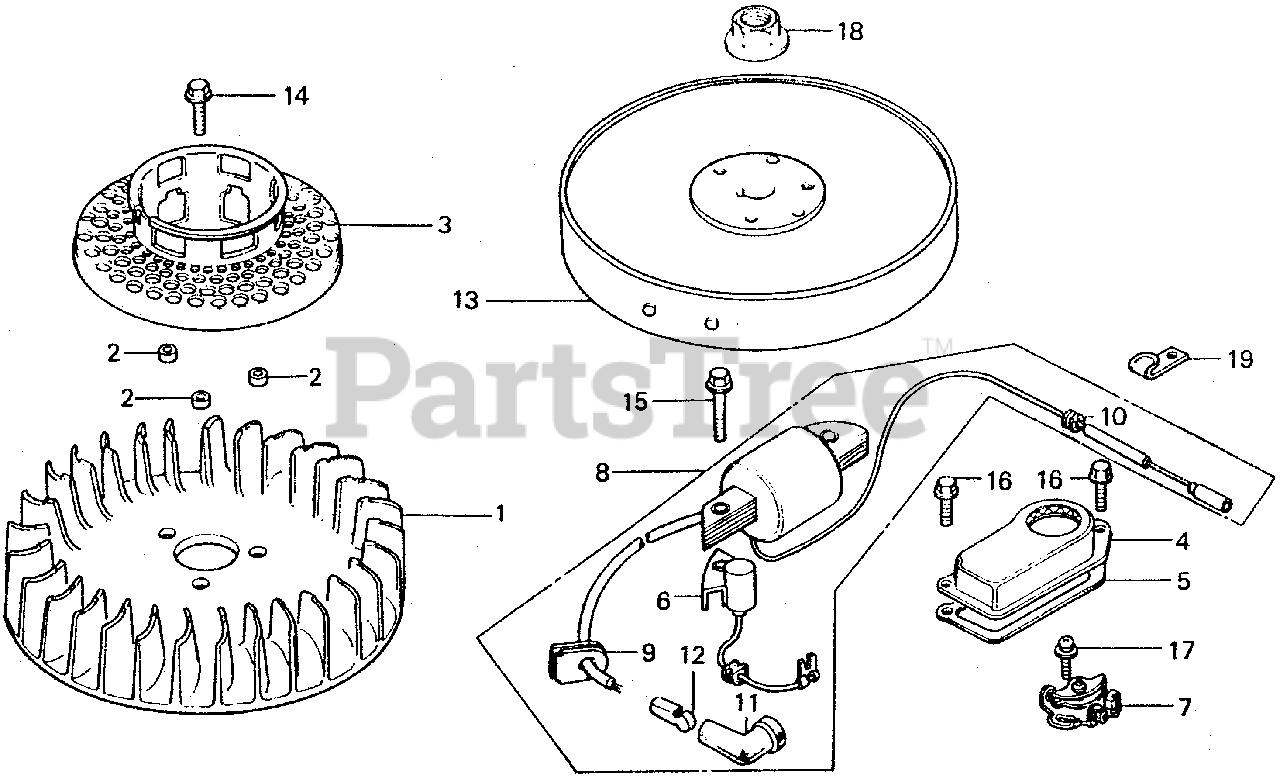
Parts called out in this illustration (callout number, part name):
1	FAN, COOLING
2	COLLAR, FAN
3	PULLEY, STARTER
4	COVER, POINTS
5	GASKET, POINT COVER (Honda Code 0636738). (NOT AVAILABLE)
6	CONDENSER
7	POINTS ASSY.
8	COIL ASSY., IGNITION
8	COIL, IGNITION
9	GROMMET, WIRE
10	GROMMET, PRIMARY WIRE
11	CAP, IGNITION (TOYO)
12	TERMINAL, PLUG
13	FLYWHEEL
14	BOLT, FLANGE (6X16)
15	BOLT, FLANGE (6X32)
16	BOLT, FLANGE (5X10)
17	SCREW-WASHER (5X12)
18	NUT, SPECIAL (14MM)
19	CLIP, CABLE
